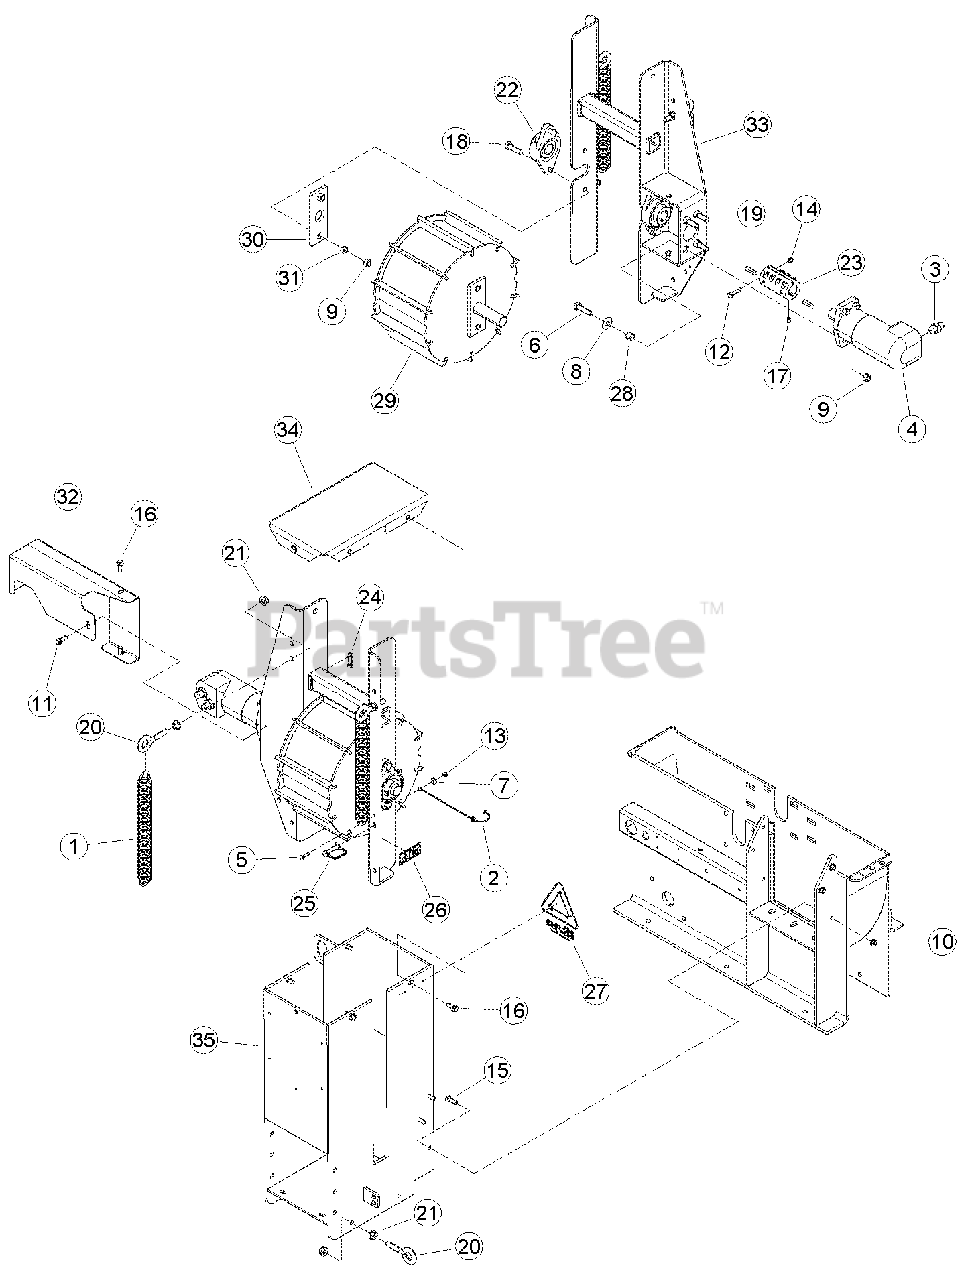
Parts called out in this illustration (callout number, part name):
1	SPRING, EXTENSION
2	LANYARD, NYLON
3	ADAPTER, -10 MORING / -8 MJIC
4	MOTOR, 24 CU IN HYDRAULIC
5	BOLT, 1/4 X 1 HEX HD GR5 ZP
6	BOLT, 1/2 X 2 HEX HD GR5 ZP
7	WASHER, 1/4 FLAT ZP
8	WASHER, 1/2 FLAT ZP
9	NUT, 1/2 CENTERLOCK GRB ZP
10	NUT, 3/8 SERR FLANGE NC ZP
11	SCREW, 3/8-16 X 1 LG THD CUTT ZP
12	BOLT, 5/16 X 1-1/2 HEX HD GR5 ZP
13	NUT, 1/4 NE NYLOCK ZP
14	NUT, 5/16 NE NYLOCK ZP
15	BOLT, 3/8 X 1-1/4 CRG GR5 NC ZP
16	BOLT, 3/8 X 1 SERR FLANGE GR5 NC ZP
17	SET SCREW, 3/8 X 1/2 CUP PT SKT
18	BOLT, 1/2 X 1-3/4 HEX HD GR5 NC ZP
19	KEY, 5/16 SQUARE X 1-1/2 LONG
20	EYEBOLT, 1/2 X 2" ZP
22	BEARING, 1-1/4" DIA 2 BOLT FLANGE
23	COUPLER, 1-1/4" SHAFT
24	WEAR PAD, STD.SPRING HD FRONT
25	PIN, 3/8 X 1-1/2 SNAP USABLE LGH
26	DECAL, CRUSHING ISO
27	DECAL, CHIP IT
28	SPACER, 0.75 X 0.620
29	ASSEMBLY, TOP GRAB ROLLER SERVICE PART
30	BEARING, SLIDE
31	SPACER, .75 OD X .5 ID X .37
32	WELDMENT, HYD MOTOR COVER
33	WELDMENT, ROLLER SLIDE
34	WELDMENT, TOP ROLLER COVER
35	WELDMENT, ROLLER SUPPORT
